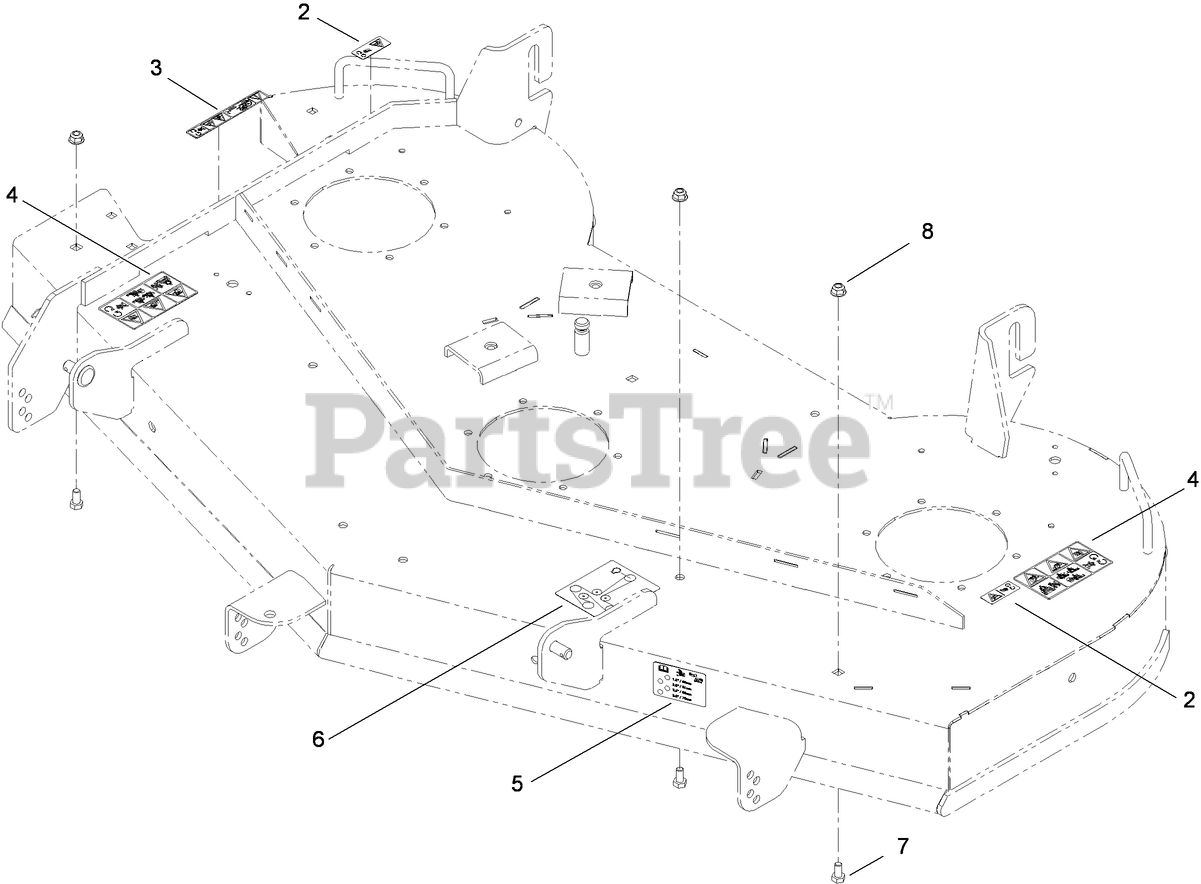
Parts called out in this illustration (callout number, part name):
2	DECAL-DANGER
3	DECAL-DANGER
4	DECAL-DANGER
5	DECAL-SCALP, ANTI
6	DECAL-ROUTING, BELT
7	SCREW-HH
8	NUT-HF, NI
